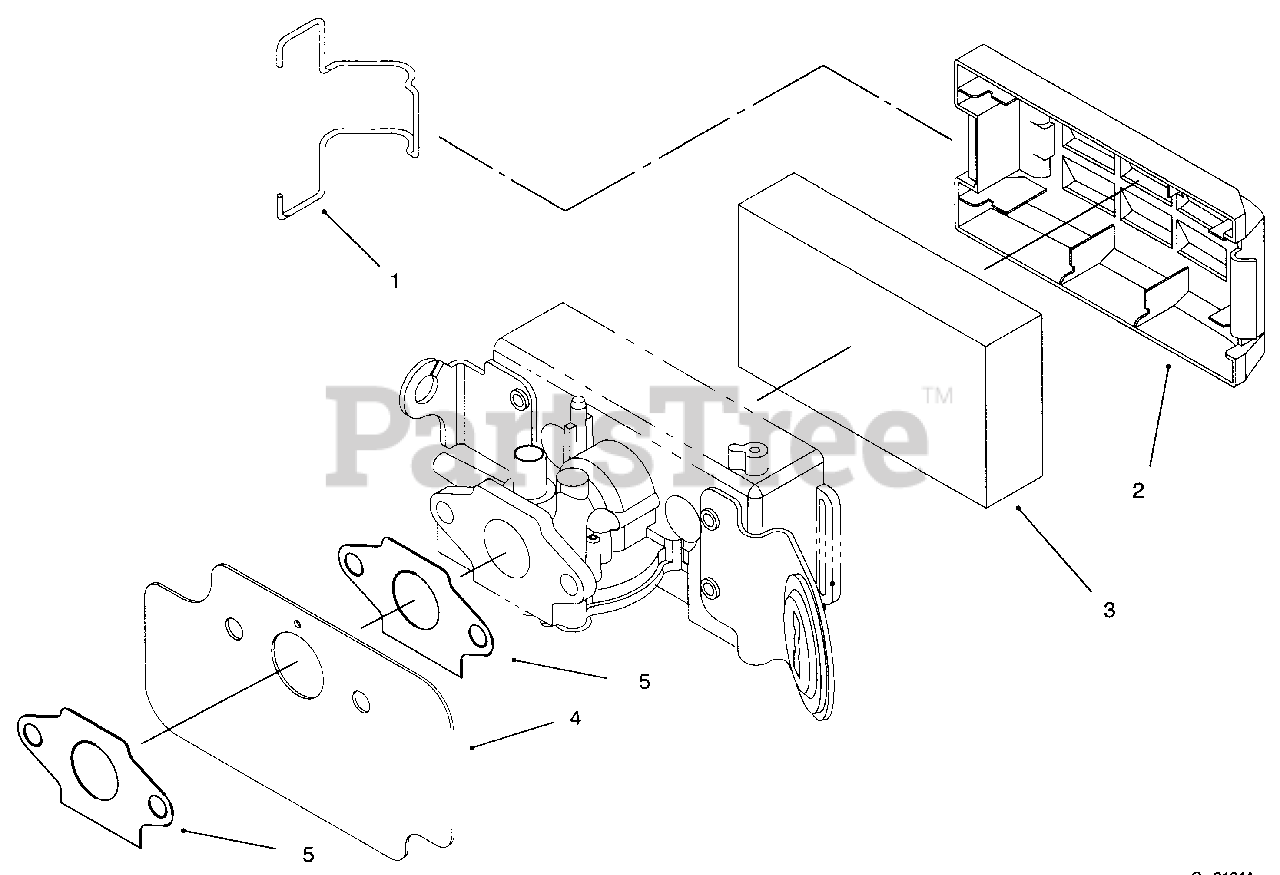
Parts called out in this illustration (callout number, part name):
1	Retainer-Cover
2	Cover-Air Filter
3	Element-Air Filter
4	Shield-Heat
5	Gasket-Carb.
